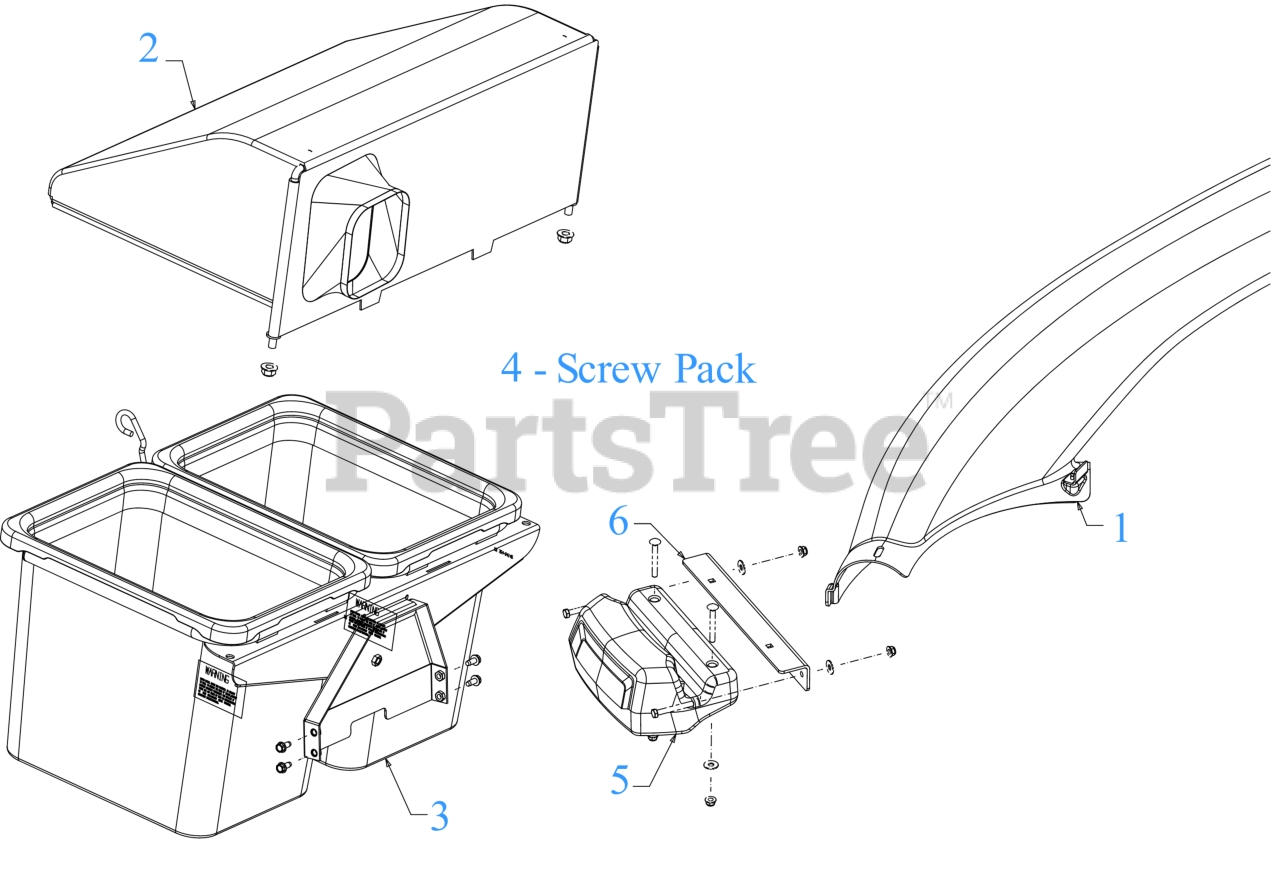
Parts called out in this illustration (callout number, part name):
1	BAG CHUTE ASSEMBLY
2	TOP COVER ASSEMBLY
3	FRAME ASSEMBLY
4	SCREWPACK
5	COUNTERWEIGHT
6	MOUNT BRACKET
